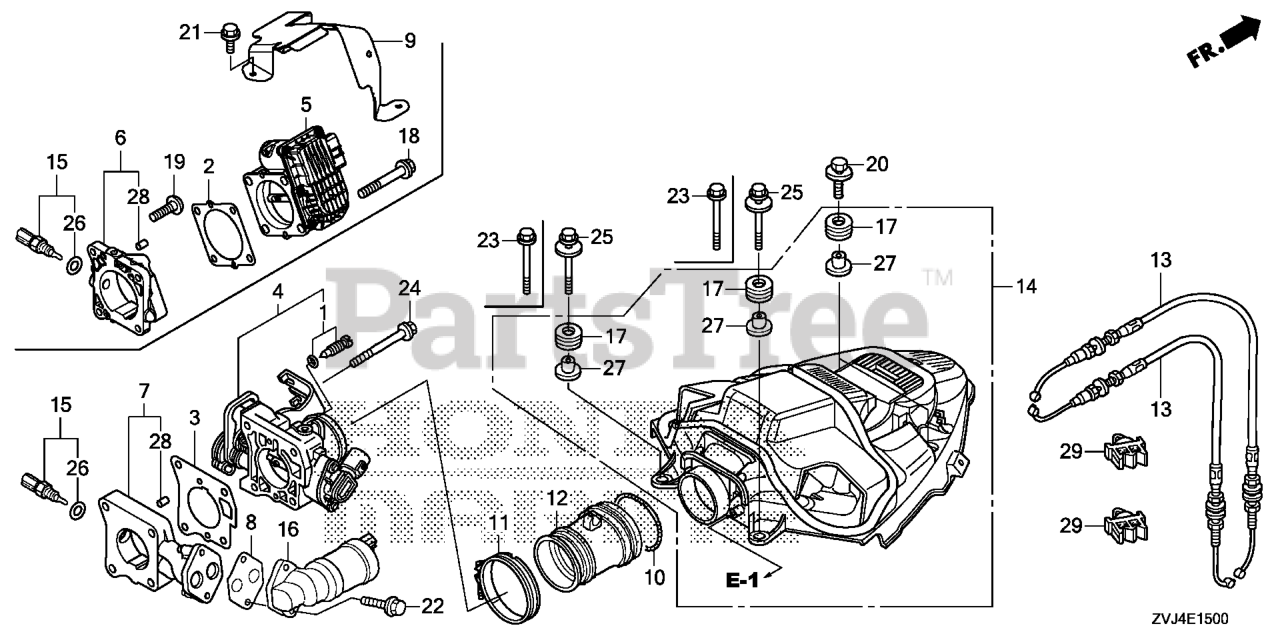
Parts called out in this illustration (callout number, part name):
2	GASKET, THROTTLE BODY
5	THROTTLE BODY, ELECTRONIC CONTROL
6	SPACER, THROTTLE BODY
9	GUARD, THROTTLE BODY
10	SPRING, AIR FLOW TUBE
11	BAND, AIR FLOW
12	GROMMET, MUFFLER
14	COVER ASSY., COOLING FAN
14	COVER, COOLING FAN
15	SENSOR ASSY., AIR TEMPERATURE
17	GROMMET, CASE (LOWER)
18	BOLT, FLANGE (8X55)
19	BOLT, SOCKET (8X25)
20	BOLT-WASHER (6X25)
21	BOLT, FLANGE (6X14)
23	BOLT, FLANGE (6X60)
27	COLLAR, MODULE IGNITION CONTROL CASE (CDI)
27	COLLAR (12X6.5)
28	PIN A, DOWEL (6X10)
